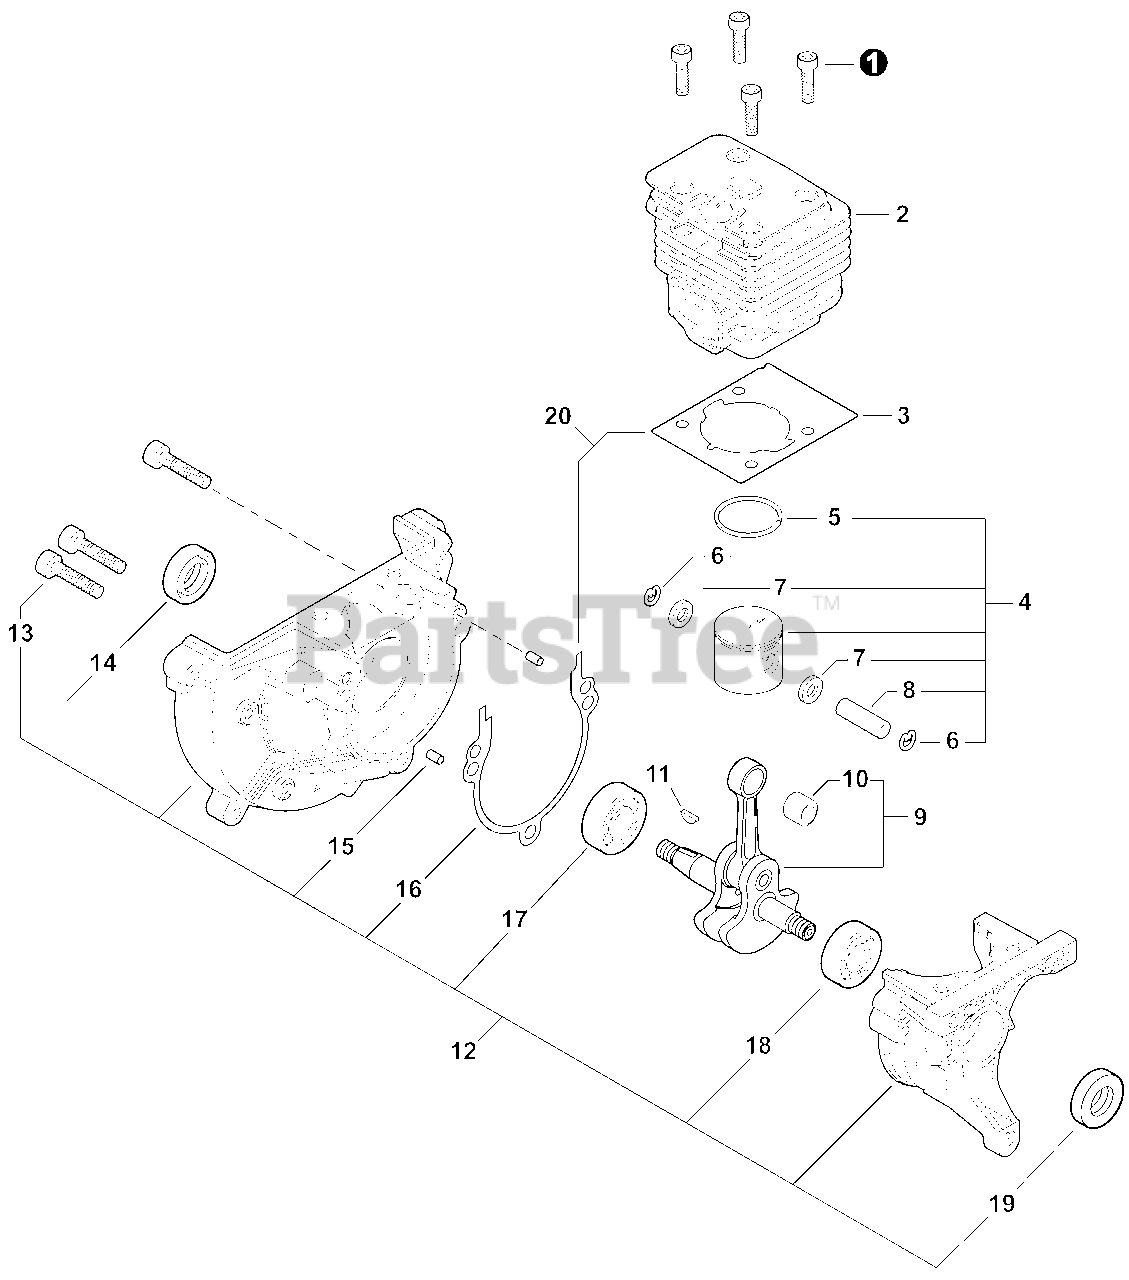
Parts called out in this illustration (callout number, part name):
1	BOLT, TORX 5×20
2	CYLINDER
3	GASKET, CYLINDER
4	PISTON KIT
5	RING, PISTON
6	RING, SNAP
7	WASHER, THRUST
8	PIN, PISTON
9	CRANKSHAFT ASSY
10	BEARING, NEEDLE 9
11	KEY, WOODRUFF
12	CRANKCASE ASSY
13	BOLT, TORX 5×25
14	SEAL, OIL 12
15	PIN, LOCATING 4×8
16	GASKET, CRANKCASE
17	BEARING, BALL 6001
18	BEARING, BALL
19	SEAL, OIL
20	GASKET KIT
